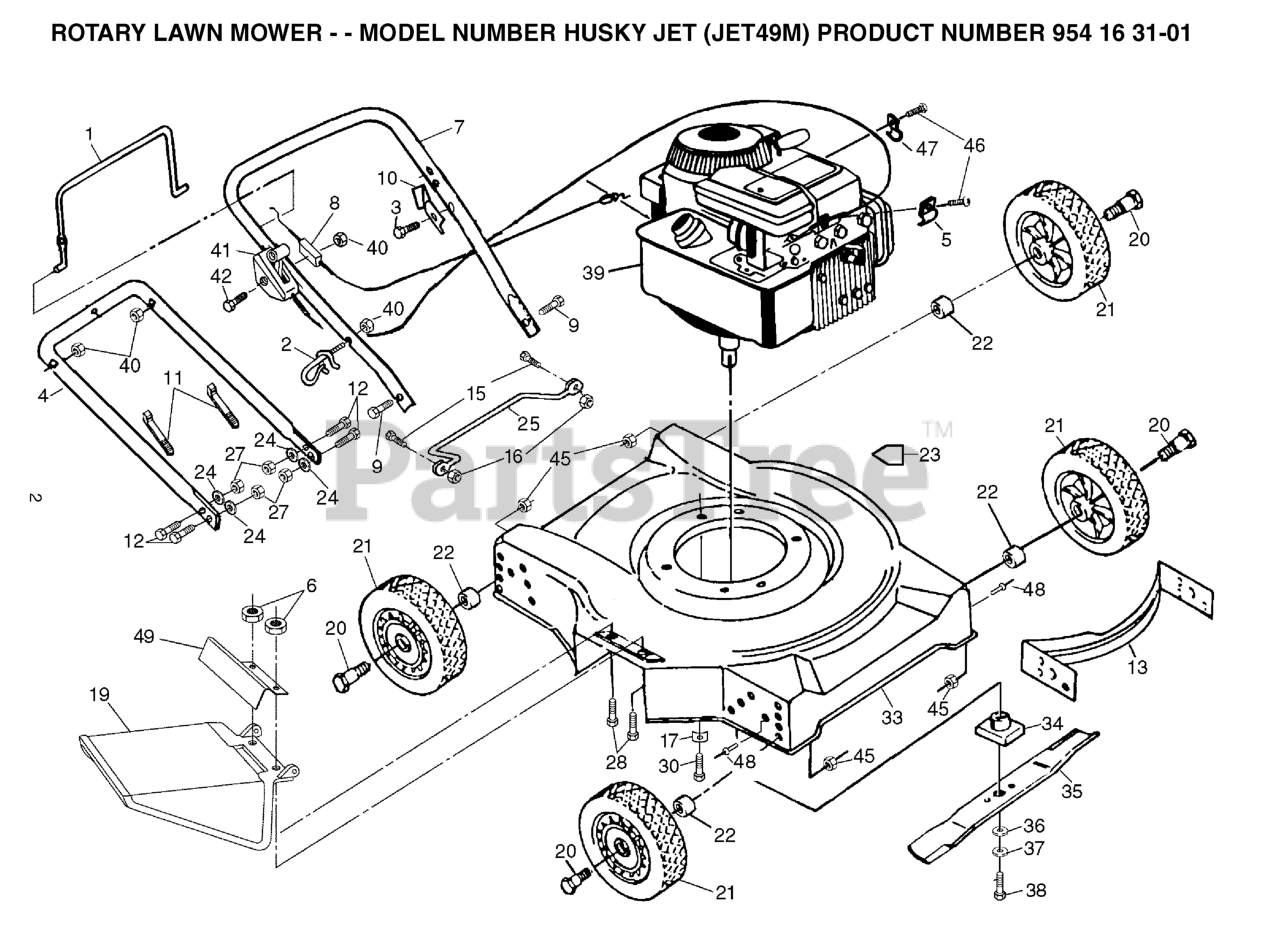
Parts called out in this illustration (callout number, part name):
1	CONTROL BAR
2	ROPE, GUIDE
5	WASHER
6	NUT
8	CABLE.CONTROL.MZR.RH.SP/PUSH
9	BOLT
10	BRACKET UPSTOP
11	TIE GUIDE
13	FRONT BAFFLE
15	REPL BY 817 02 10-08
17	WASHER.ENGINE.BZP
21	WHEEL
22	SPACER.WHEEL.390.X1.0X.380.RTA
23	DECAL.INTERNATIONL.CUTFINGER
27	FLANGED LOCKNUT 3/8-16 ZINC
28	BOLT.HEX.1/4.X.3/4.DICHROMATE
30	BOLT 3/8-16X1-1/8
34	BLADE ADAPTOR
35	20" Blade
36	WASHER,HARDEN
37	LOCKWASHER
38	SCREW, HEX HD 3/8-24 X 1-3/8
40	NUT
42	SCREW.PAN.HEAD
45	LOCKNUT PM
46	SCREW.HEX.HEAD.WASHER.10-16
47	GUIDE CLIP PM
48	RIVET BLIND
